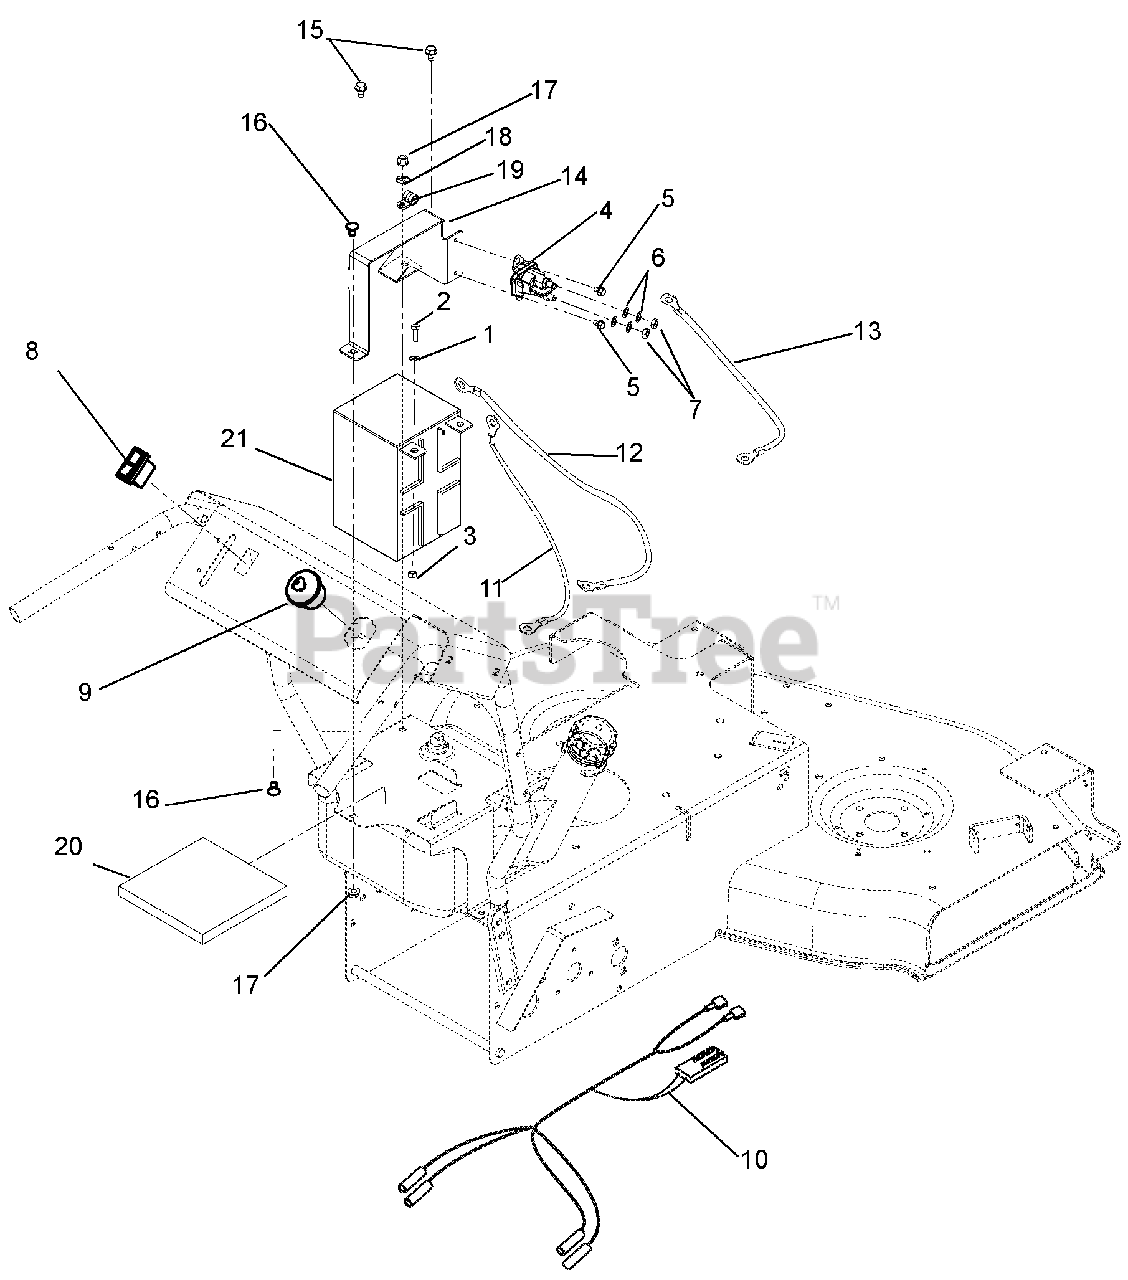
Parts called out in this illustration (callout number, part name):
1	@WSHR-FL-STL.281X.62X.065 YWZC
2	@BLT-HEX .25-20X.75 GR5 YWZC
3	NUT-KEPS .250-20
4	SOLENOID
5	@SCR-TAP .25-20X.37 HWH YWZ TR
6	WSHR-LOCK INT .31 YWZC
7	NUT-JAM .31-24 YWZC
8	SWITCH-ROCKER, MOMENTARY
9	KEYSWITCH-IGNITION 3 POS
9	BRKT, STRIPER MOUNT-RIGHT
10	HARNESS, WAW WIRING
11	ASSY, POS BATTERY 6.75"
12	CABLE, NEGATIVE 26" 6 GA.
13	CABLE, POS. BAT 18.50"
14	BRKT, BATTERY MOUNT
15	@SCR-TAP .31-18X.50 HWH TR YWZ
16	@BLT-RDHDSQNK .31-18X.50 G5YZ
17	@NUT-LK-TOP-FLG .31-18 YWZC
18	NUT-PUSH .312
19	CLAMP, CUSHIONED STEEL
20	BATTERY MAT WAW 2012
21	BATTERY, 12V 20HR;190CCA GEP
